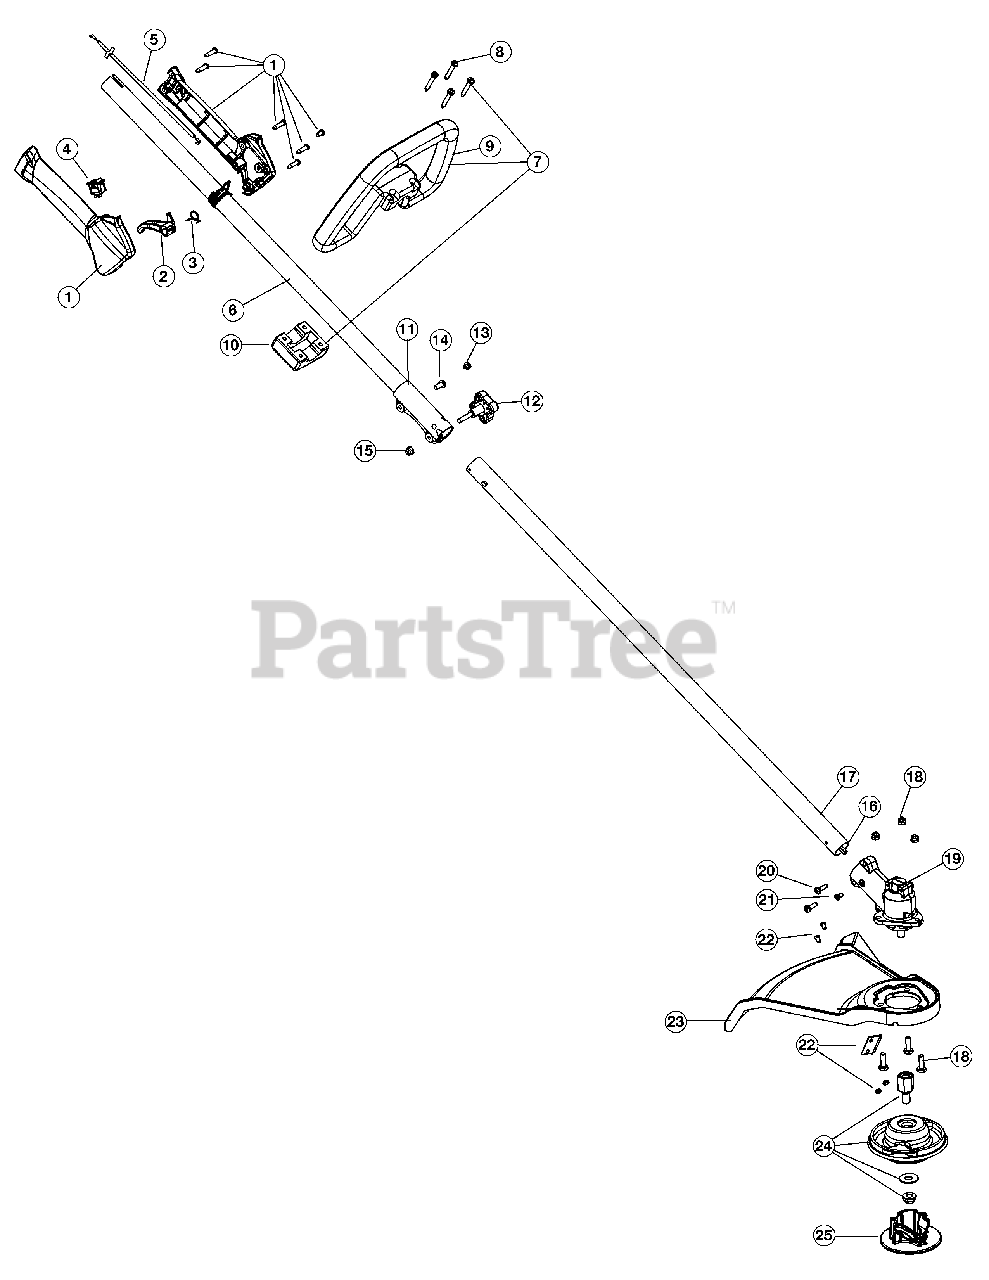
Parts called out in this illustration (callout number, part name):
1	Throttle Housing Assembly (includes 2-4)
2	Throttle Trigger
3	Throttle Trigger Spring
4	Switch Assembly
5	Throttle Cable Assembly
6	Upper Drive Shaft Housing
7	Deluxe D-Handle Assembly (includes 8-10)
9	D-Handle
10	D-Handle Base
11	Split Boom Coupler (includes 12-15)
12	Adjustment Knob (includes 15)
15	Nut
16	Lower Flexible Drive Shaft
17	Lower Drive Shaft Housing
18	Shield Mount Screw Assembly
19	Gearbox Assembly
20	Gearbox Screw
21	Anti-Rotation Screw
22	Blade Assembly
23	Shield Assembly (includes 22)
24	Cutting Head Assembly
25	Cutting Head Cap
